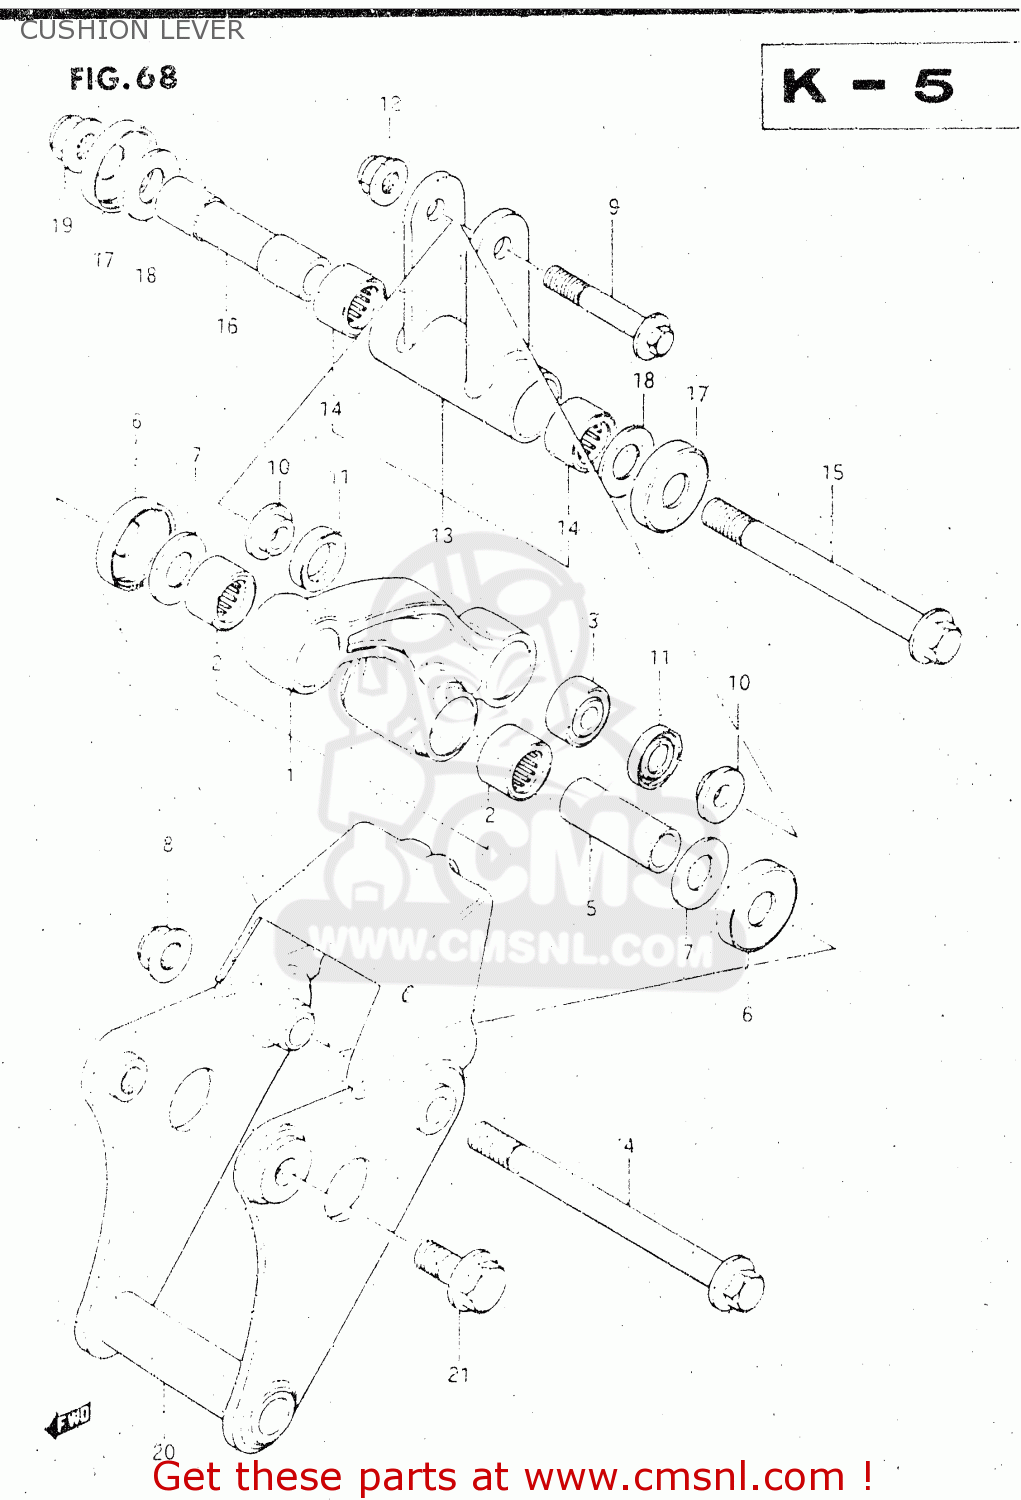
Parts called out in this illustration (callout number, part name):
1	LEVER SET,REAR CUSHION
2	ROLLER BEARING (17X24X2
3	BEARING(10X24X15)
4	SHAFT,REAR CUSHION LEVER
5	SPACER,REAR CUSHION LEVER
6	COVER,RR SWGARM DUST SEAL
7	WASHER
8	NUT 12MM
9	BOLT(10X52)
10	SPACER
11	DUST SEAL,RR CUSHION LEVER RR
12	NUT
13	LEVER SET,REAR CUSHION
14	ROLLER BEARING (17X24X2
15	BOLT,REAR CUSHION ROD
16	SPACER,REAR CUSHION ROD
17	COVER,RR SWGARM DUST SEAL
18	WASHER
19	NUT 12MM
20	HOLDER
21	BOLT(12X23)
